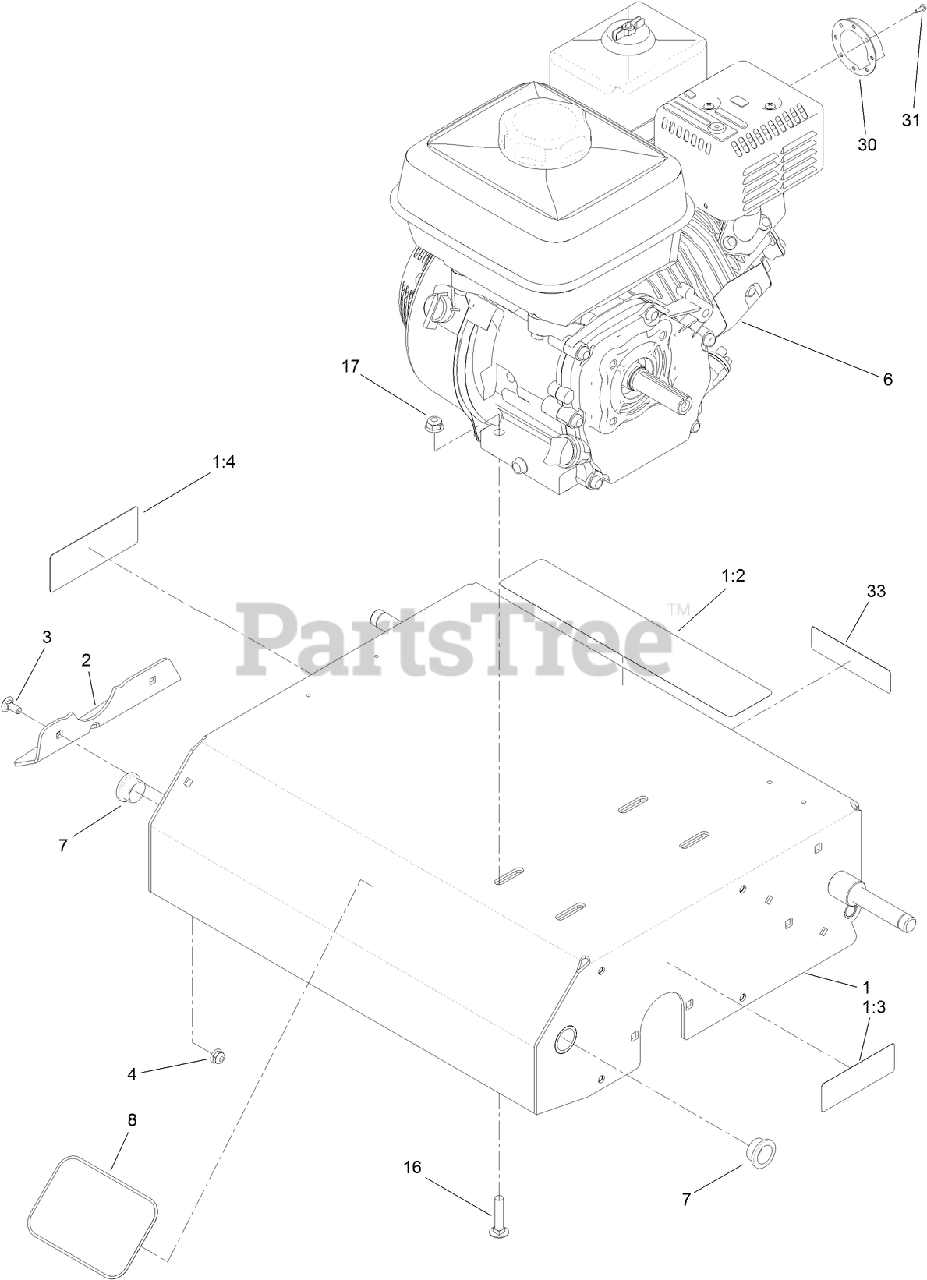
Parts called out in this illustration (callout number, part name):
1	FRAME ASM
1:2	DECAL-WARNING
1:3	DECAL-WARNING
1:4	DECAL-DANGER
2	GUARD-HAND
3	SCREW-CARR
4	NUT-HF
6	ENGINE-HONDA, GX160
7	BUSHING
8	DECAL
16	BOLT-CARR
17	NUT-HF, NI
30	DEFLECTOR
31	SCREW-PPHTF
33	DECAL-ARRESTER, SPARK
